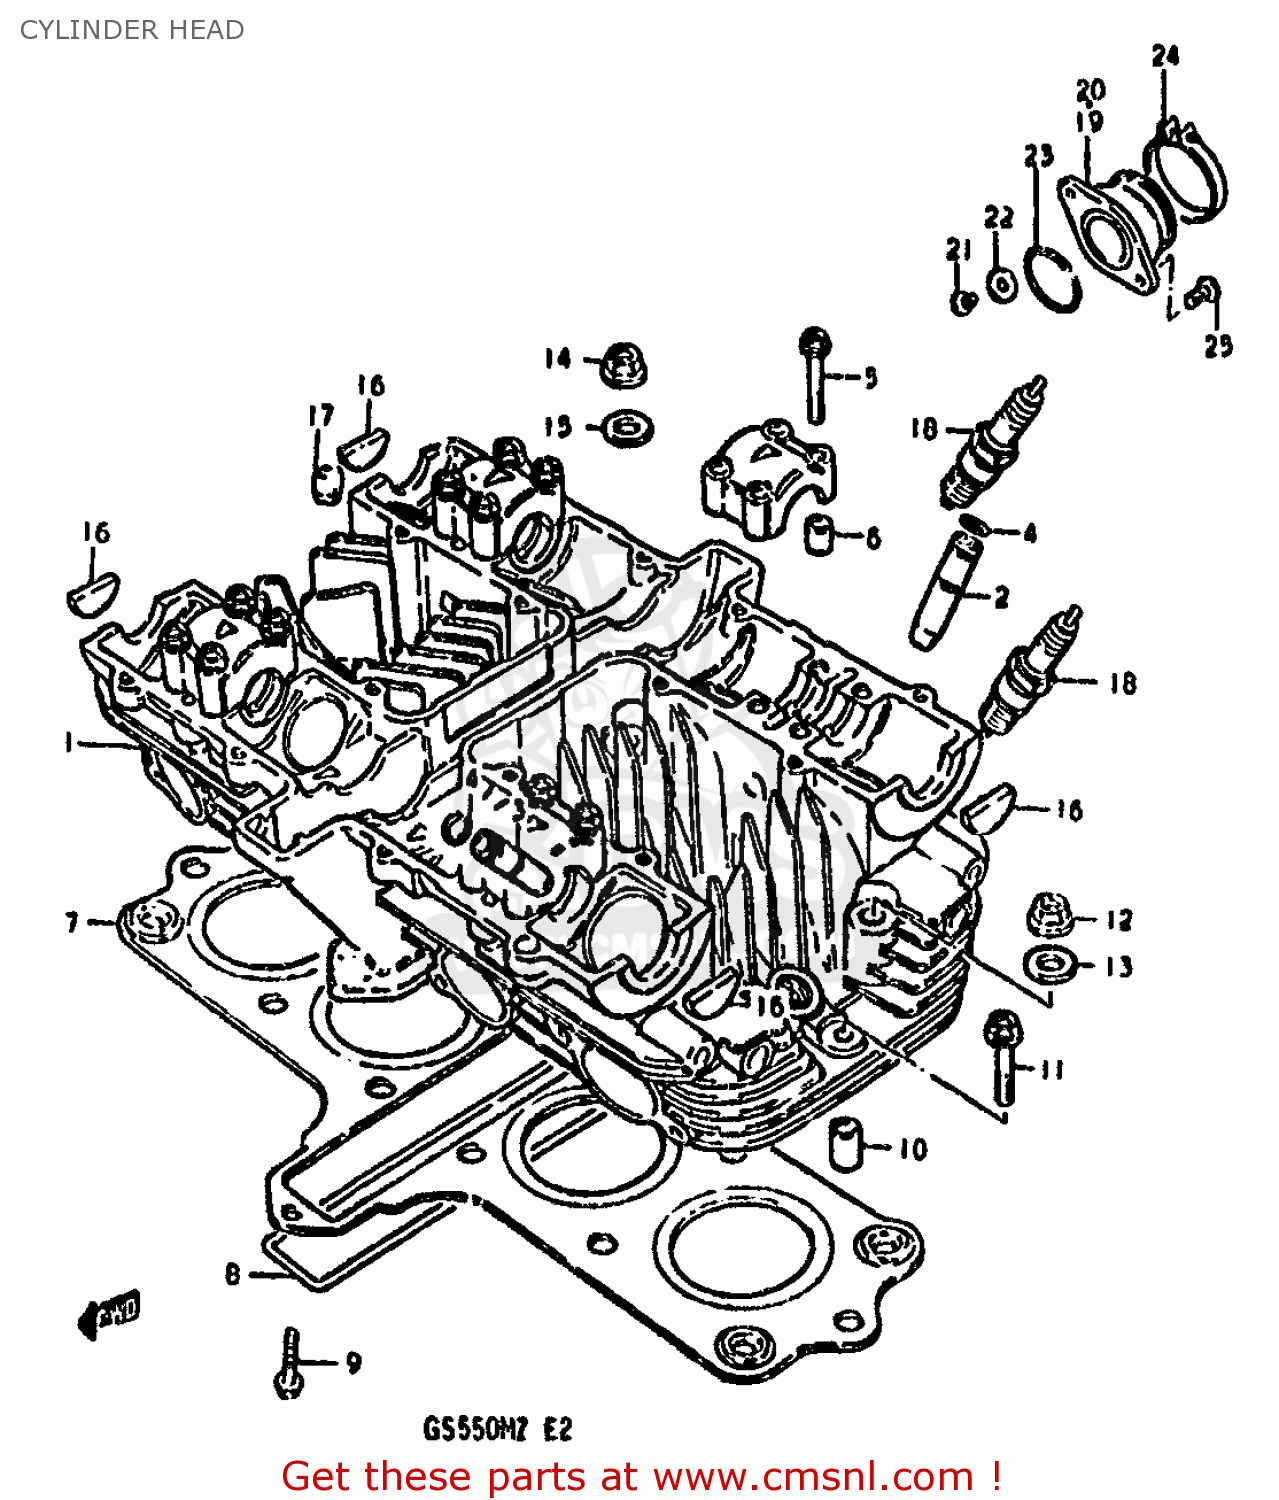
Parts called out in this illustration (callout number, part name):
1	HEAD SET,CYLINDER
2	GUIDE,INTAKE VALVE
3	GUIDE,EXHAUST VALVE
4	RING,SNAP
5	BOLT(6X39)
6	PIN(6.2X8X11)
7	GASKET,CYLINDER HEAD (MCA)
8	O RING(D:3,ID:26X157)
9	BOLT
10	PIN
11	BOLT,UNDER
12	NUT
13	GASKET (NAS)
14	NUT
15	WASHER(8.5X19X2.3)
16	PLUG
17	PAD
18	SPARK PLUG
19	PIPE,INTAKE,R
20	PIPE,INTAKE,L
21	BOLT
22	WASHER
23	O-RING
24	CLAMP
25	SCREW
